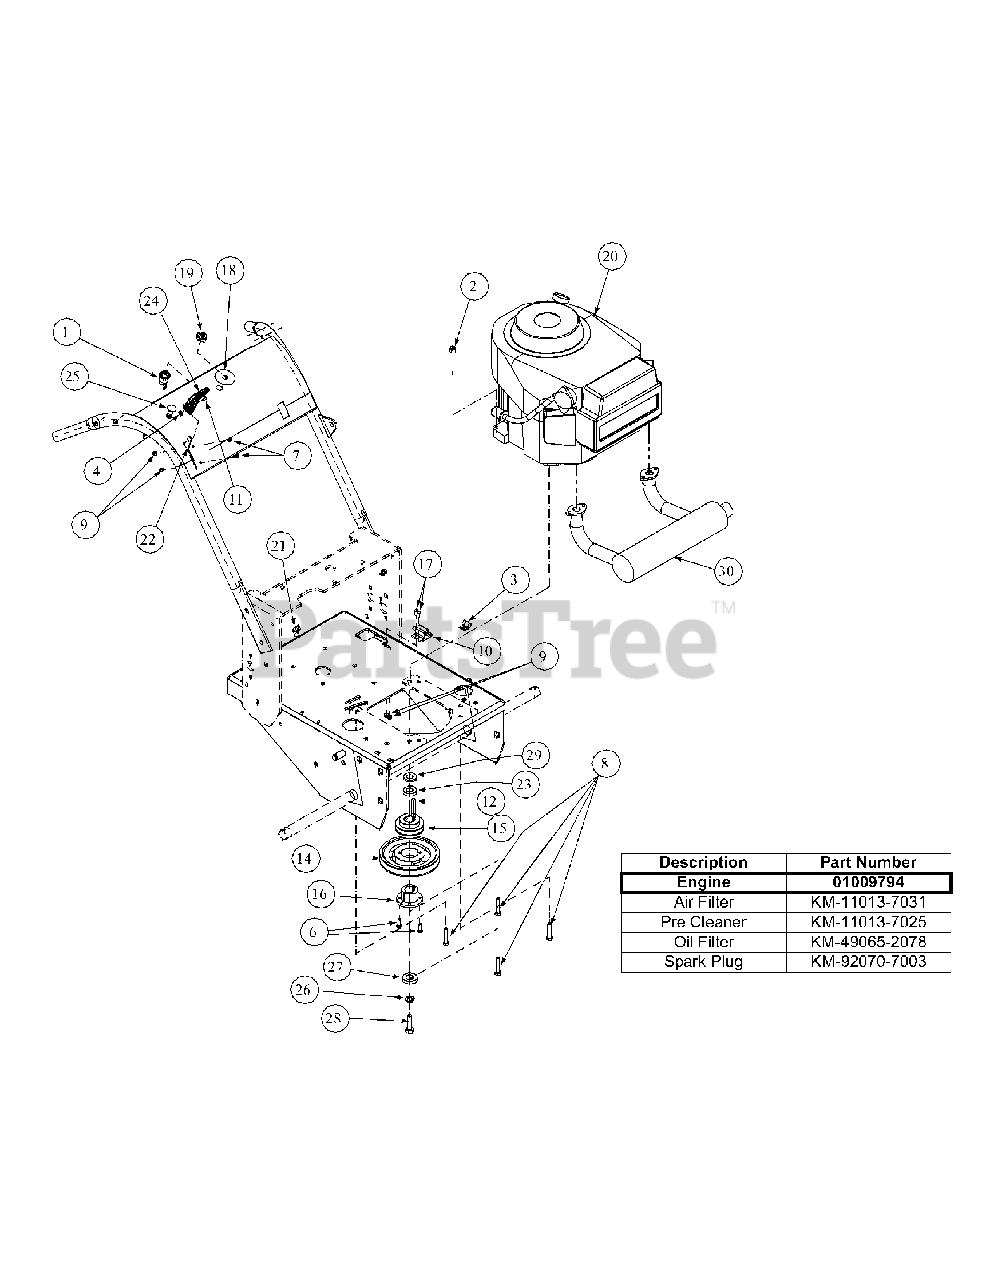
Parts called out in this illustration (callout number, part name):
1	Single Ignition ON/OFF Switch
1	Ignition ON/OFF Switch
2	Lock Nut, Nylon Insert, 5/16-18
3	Support Clamp
4	Nut, 8-32, w/ Star Washer
6	Hex Cap Screw, 1/4-20 x 3/4
7	Screw, Hex Washer, 10-32 x 1/2
8	HHCS, 5/16-18 x 2
9	Lock Nut, Nylon Insert, 10-32
10	Delta Switch
11	Machine Screw, 8-32 x 3.8
12	Key Stick, 1/4 x 1/4 x 2-3/4
13	Harness Wire
14	Deck Pulley
15	Traction Pulley
17	Machine Screw, 10-32 x 5/8
18	Decal, Pull Start Overlay
19	Nut w/cap, 5/8-32 Ignition
20	13 Hp Kawasaki Kai Engine
21	Support Clamp, 3/8 OD
22	Throttle Control Cable
23	Flat Washer
24	Throttle Control Knob
25	Choke Cable
26	Lock Washer, 7/16
27	Clutch Washer
28	Hex Cap Screw, M10 x 1.5, 30mm, GR10.9
29	Spacer, Engine Pulley
